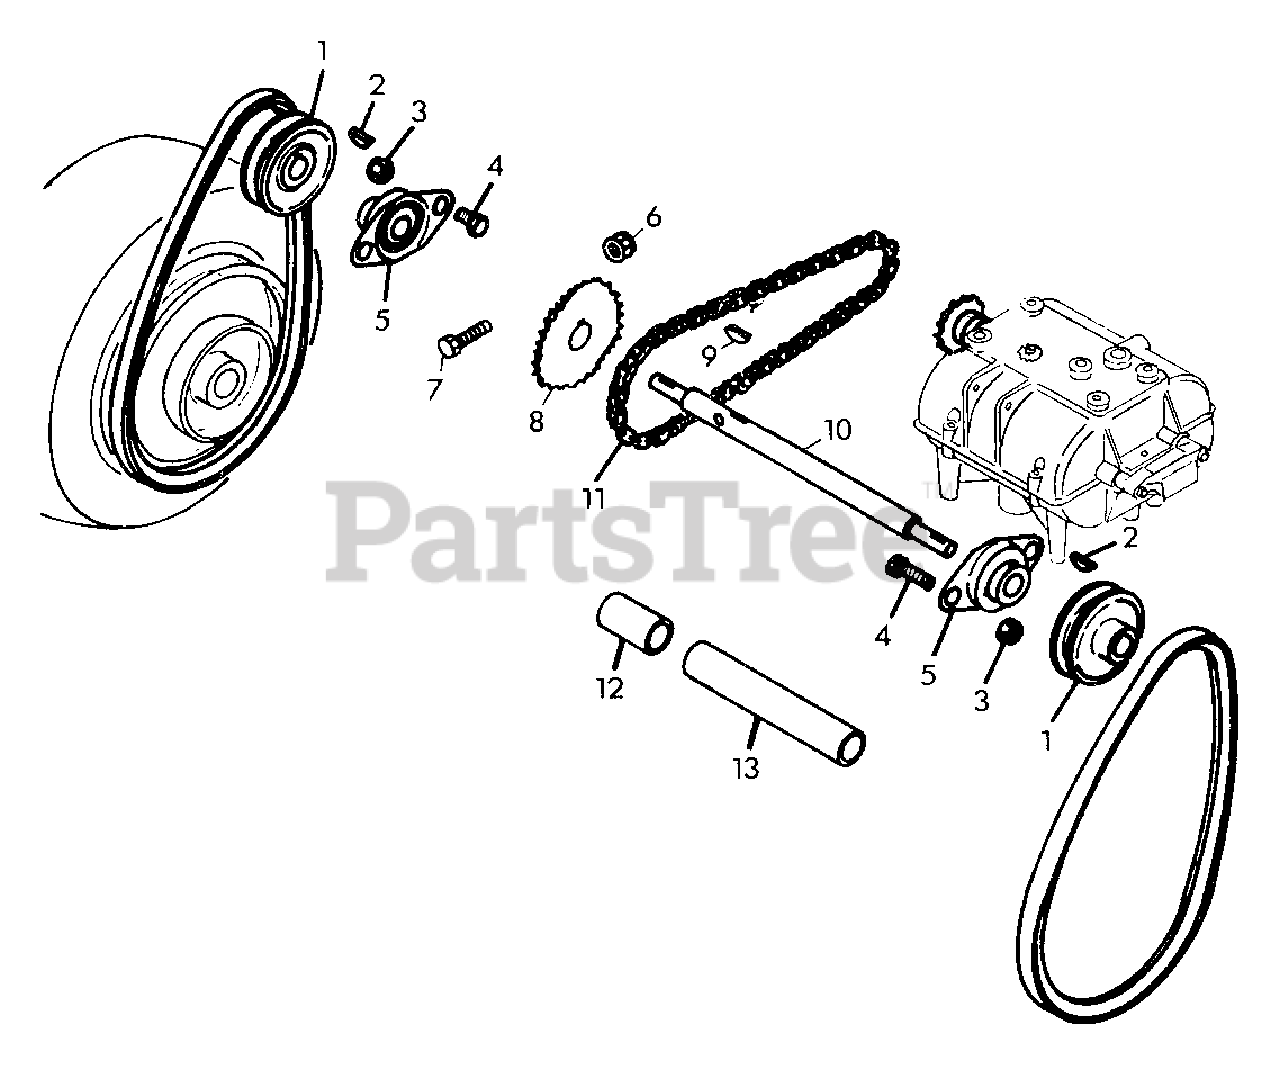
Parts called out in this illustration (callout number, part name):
1	Pulley, Jack-Shaft
2	Key, Woodruff 3/16x.750 Hard
3	Nut, Lock 3/8-16
4	Bolt, Hex 3/8-16x.75
5	Bearing, Fan
6	Nut, Lock 1/4-20
7	Bolt, Hex 1/4-20x2.25
8	Sprocket, 28T .5 Pitch
9	Key, Woodruff .25x.75 Hard
10	Shaft, Jack
11	Chain, No. 40
12	Tube, Plastic
13	Tube, Plastic
